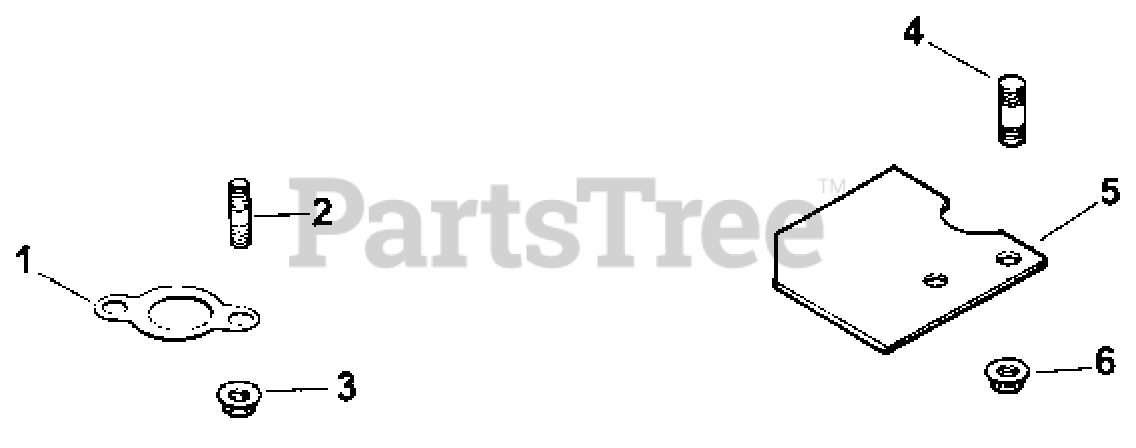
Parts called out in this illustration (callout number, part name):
1	Stud (M8 x 1.25 x 33)
2	Exhaust Gasket
3	Muffler Mounting Nut (M8 x 1.25)
4	Exhaust Stud
5	Heat Deflector
6	Hex Flange Nut (M6 x 1.0)
